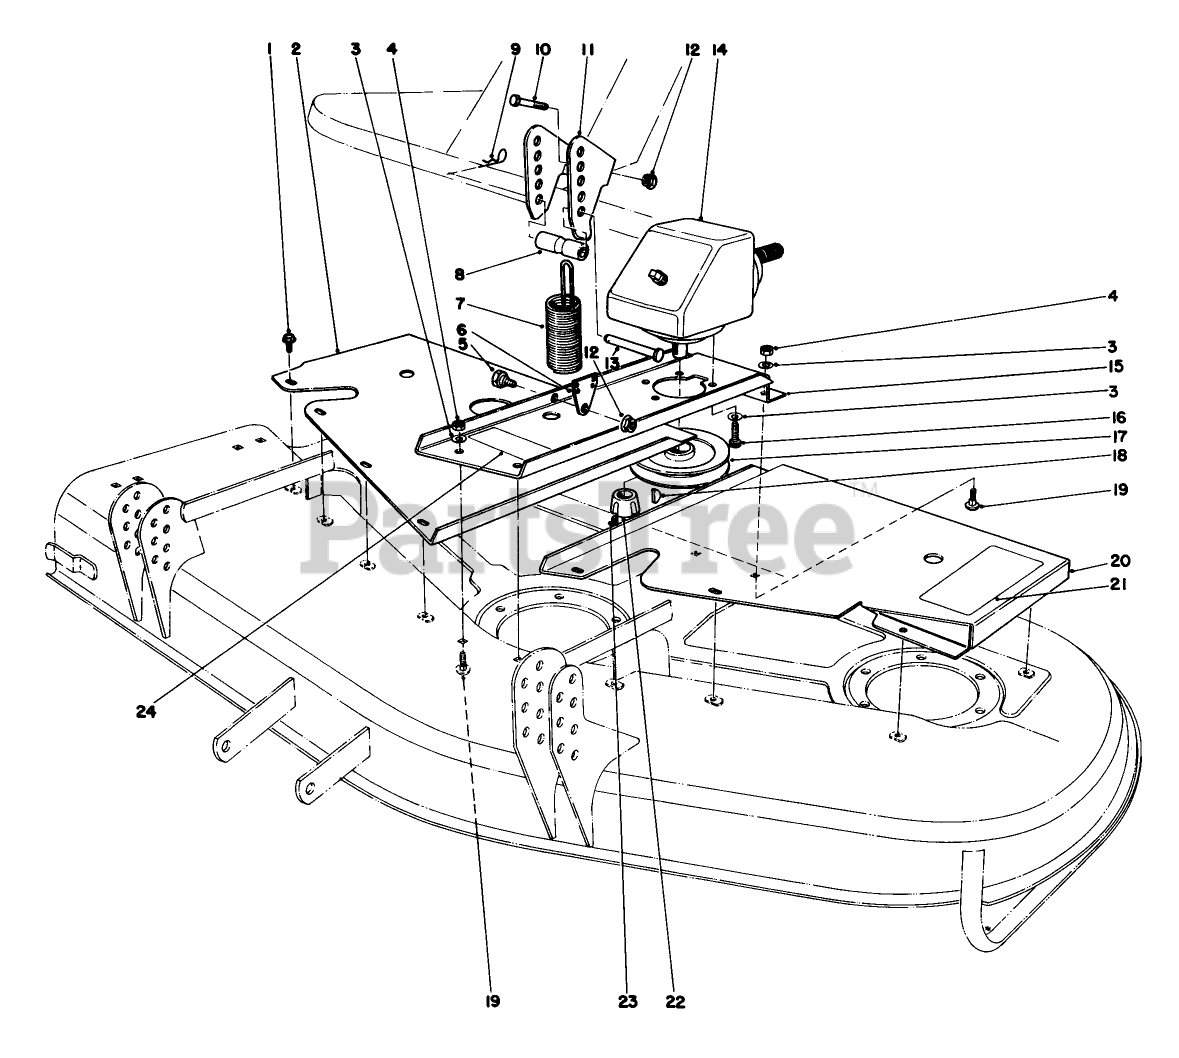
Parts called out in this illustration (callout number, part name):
1	SCREW-HHFTF
2	RH COVER WA R
3	WASHER-LOCK
4	NUT-HEX
5	BOLT-SHOULDER
6	SPRING END R
7	Spring-Extension
8	SPACER
9	PIN-HAIR
10	SCREW-HH
11	SPRING BRACKET R
12	NUT-HHF, WHIZ
13	PIN-CLEVIS
14	GEAR BOX ASM
15	Base-Bear Box
16	SCREW-HSH
17	PULLEY WA BO
18	KEY-WOODRUFF
19	SCREW-CARR
20	LH COVER WA R
21	DECAL
22	BUSHING-LOCK, TAPER
23	SCREW-SET, HSH
24	Decal-Caution
